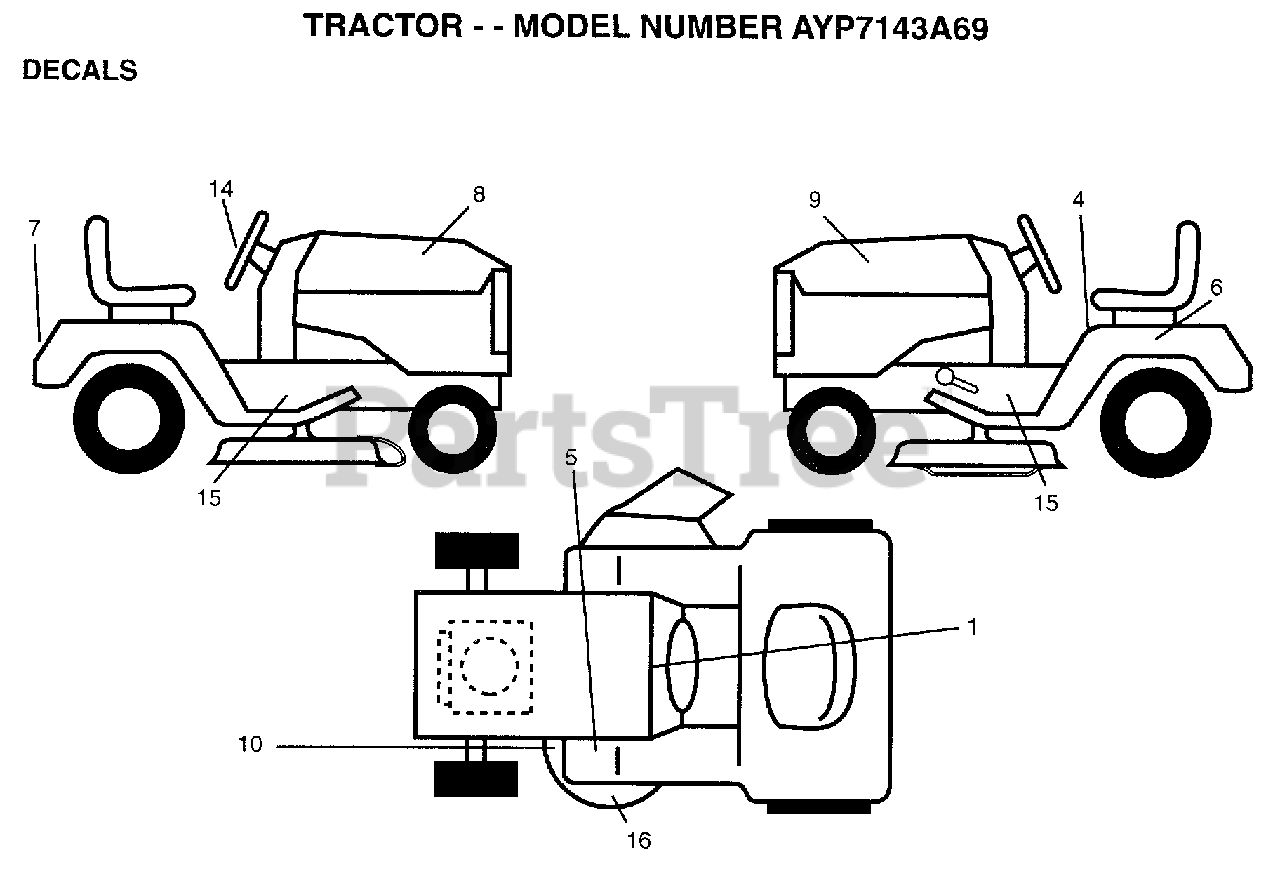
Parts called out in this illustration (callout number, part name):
4	DECAL
6	DECAL.BATRY.3-3908
8	DECAL.HD.RH.WIZAR
9	DECAL.HD.LH.WIZAR
10	DECAL
14	DECAL.INS.STRG.WL
15	DECAL CHASSIS WIZ
16	DECAL DECK WIZ +
